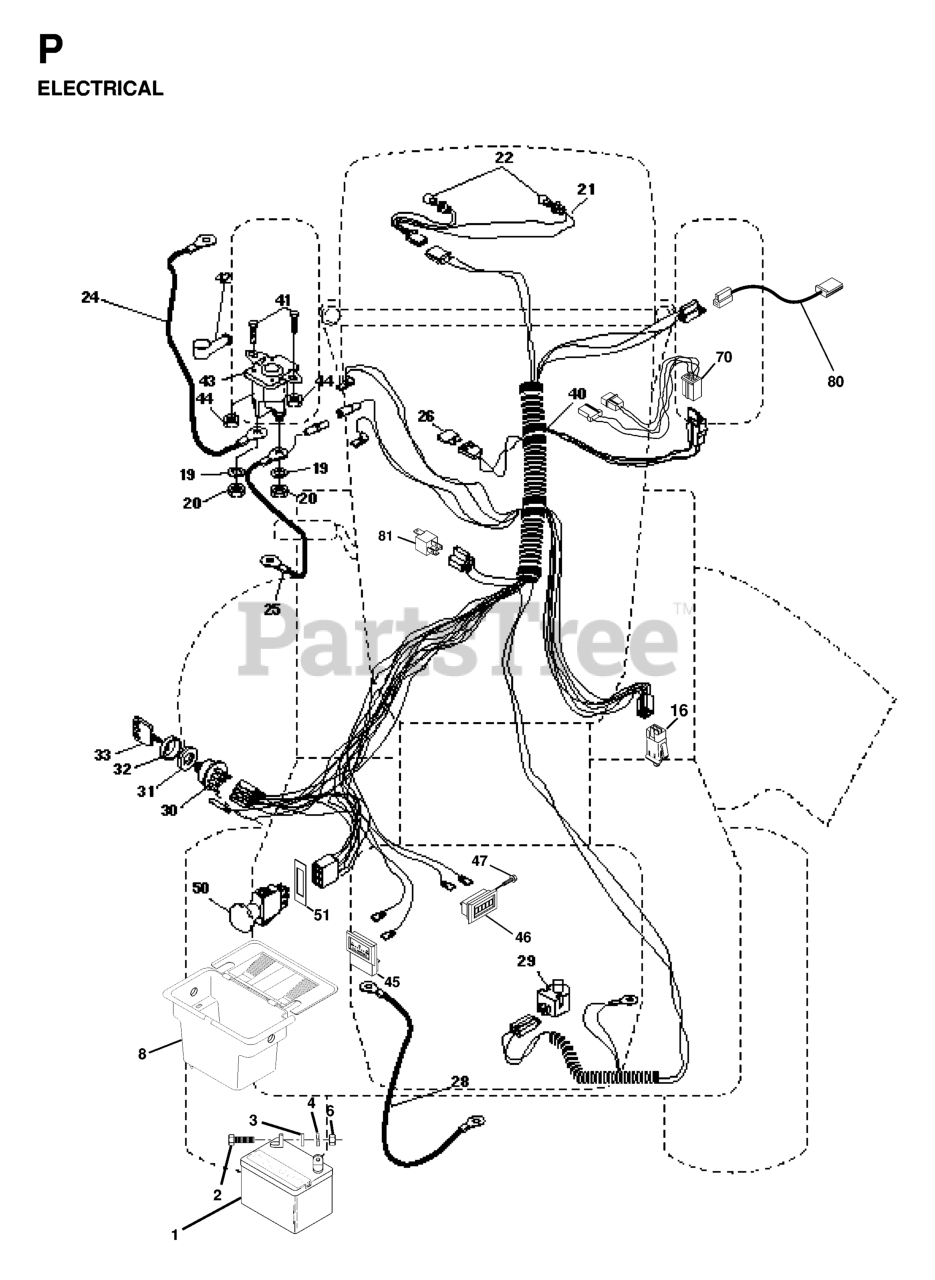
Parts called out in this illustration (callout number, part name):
1	BATTERY 12 VOLT 25 AMP
2	BOLT.HEX.1/4.X.3/4.DICHROMATE
4	LOCKWASHER
6	NUT
8	CASE BATTERY MECH HINGE
16	SWITCH INTERLOCK
19	LOCKWASHER
20	NUT
21	HARNESS LIGHT SOCKET
24	BATTERY CABLE GT
25	CABLE BATTERY
28	CABLE T
29	PLUNGER SWITCH (COLOR:OLIVE)
30	SWITCH.IGNITION.4.POSITION
31	NUT IGNITION
32	COVER SWITCH KEY
33	KEY.MOLDED.GENERIC
40	WIRING HARNESS
41	BOLT
42	TERMINAL COVER
43	SOLINOID
44	Nut, Keps Blk Hex 1/4-20 UNC
45	AMMETER
46	HOUR METER T
47	Screw 10-24 x 1/2 Black
50	SWITCH PTO 3 PDT
51	FRAME RETAINING RING
70	HARNESS ENGINE
80	HARNESS, CLUTCH
81	RELAY.ASSY.T
